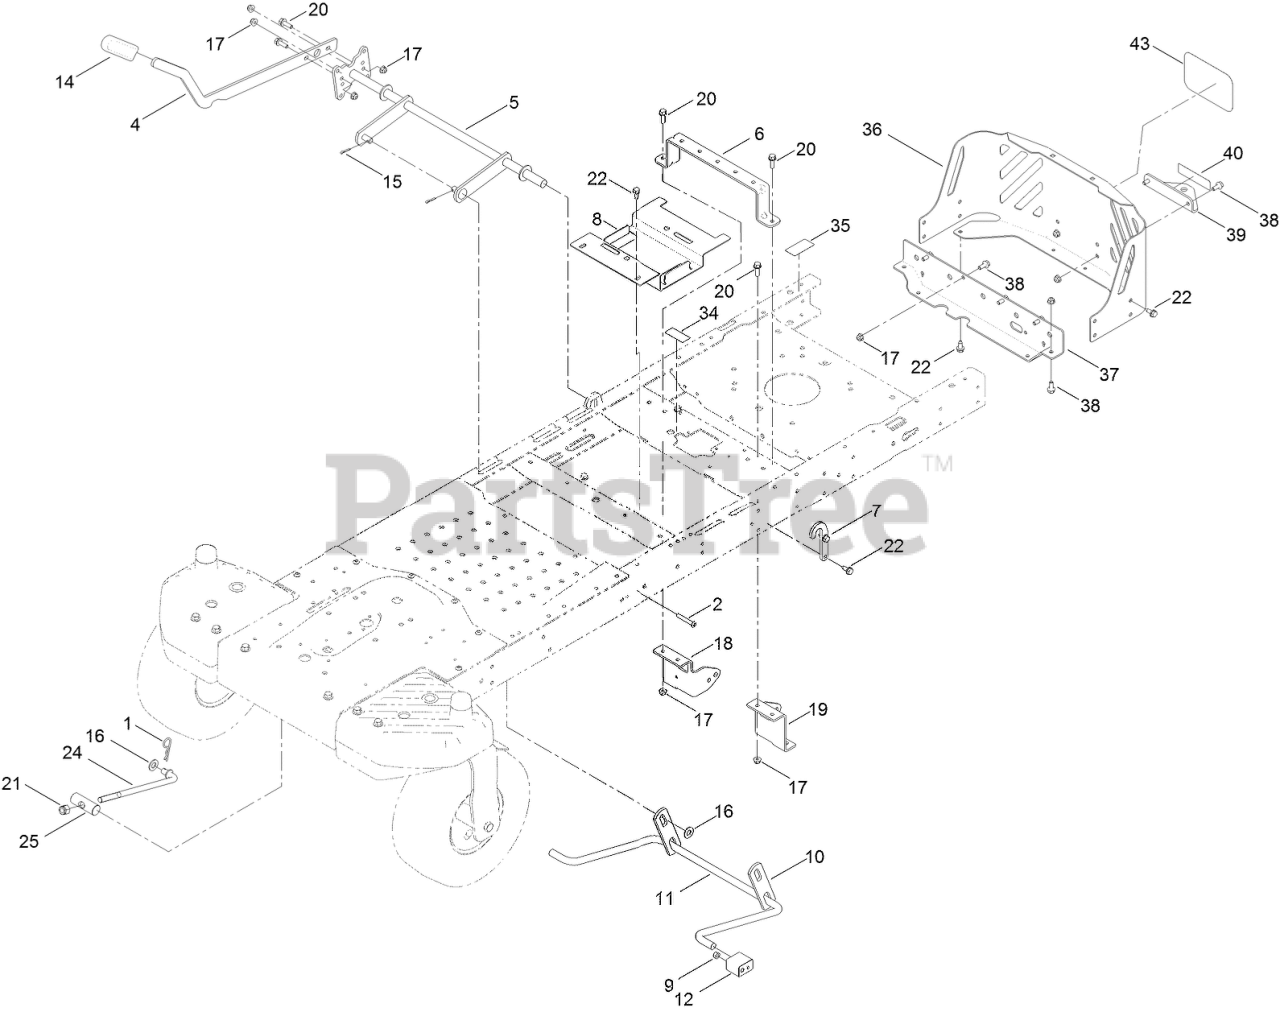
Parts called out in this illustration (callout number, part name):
1	PIN-COTTER
2	SCREW-HSBH
4	LEVER-LIFT
5	LIFT-DECK, NARROW
6	BRACE-SEAT, REAR (NARROW)
7	BRACKET-LIFT
8	BRACKET-BATTERY
9	NUT-LOCK, NI
10	LINK-LIFT
11	ARM-LIFT, REAR
12	BLOCK-PIVOT
14	GRIP-LEVER
15	PIN-COTTER
16	WASHER-FLAT
17	NUT-HF, NI
18	MOUNT-HYDRO, FRONT (RH)
19	MOUNT-HYDRO, FRONT (LH)
20	SCREW-HHF
21	NUT-HEX
22	SCREW-HWHTF
24	ROD-MOUNT, DECK
25	PIN-PIVOT
34	DECAL-LOCATION, SERVICE DEALER
35	DECAL-BYPASS
36	GUARD-ENGINE, NARROW
37	CROSSMEMBER-REAR, NARROW
38	SCREW-HHF
39	BRACKET-HITCH
43	DECAL
